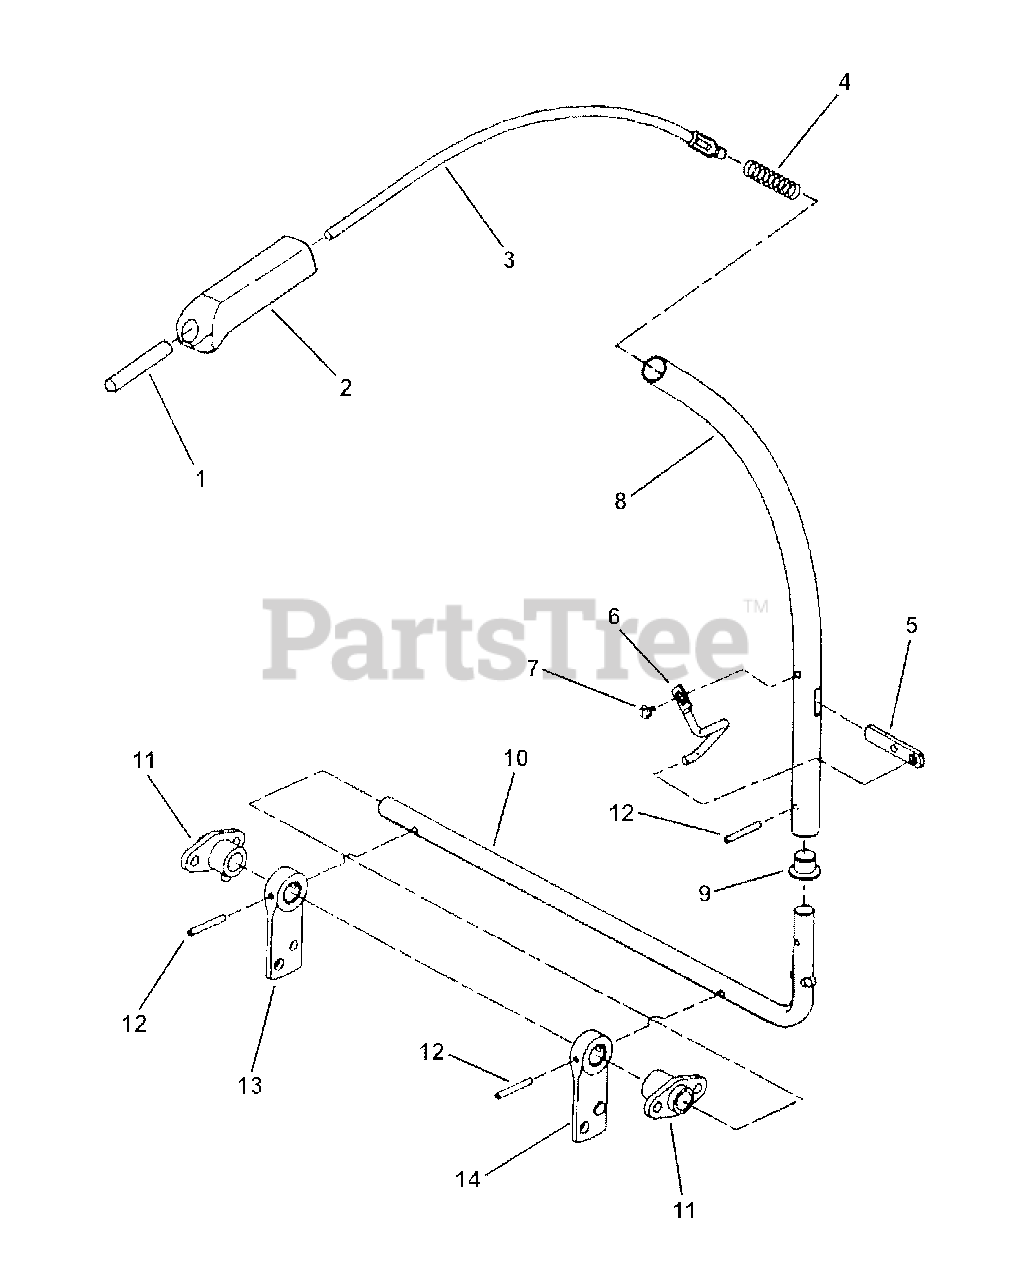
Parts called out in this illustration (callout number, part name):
1	GRIP, 5/16 x 2-1/2" Vinyl
2	GRIP, Brake/Clutch Handle
3	ROD, Park Brake
4	SPRING, Clutch/Brake Release
5	ARM, Brake/Clutch Lever
6	PIVOT, Brake/Clutch Lever
7	SCREW, 1/4-20 x 3/8" Hex Washer Self-Tap
8	TUBE, Clutch/Brake Lever
9	BUSHING, Nylon
10	ROD, Clutch/Brake
11	ASSEMBLY, Foot Shaft Pivot
12	PIN, 3/16 x 1-1/2" Roll
13	ARM, Brake/Clutch
14	WELDMENT, Brake/Clutch Arm
